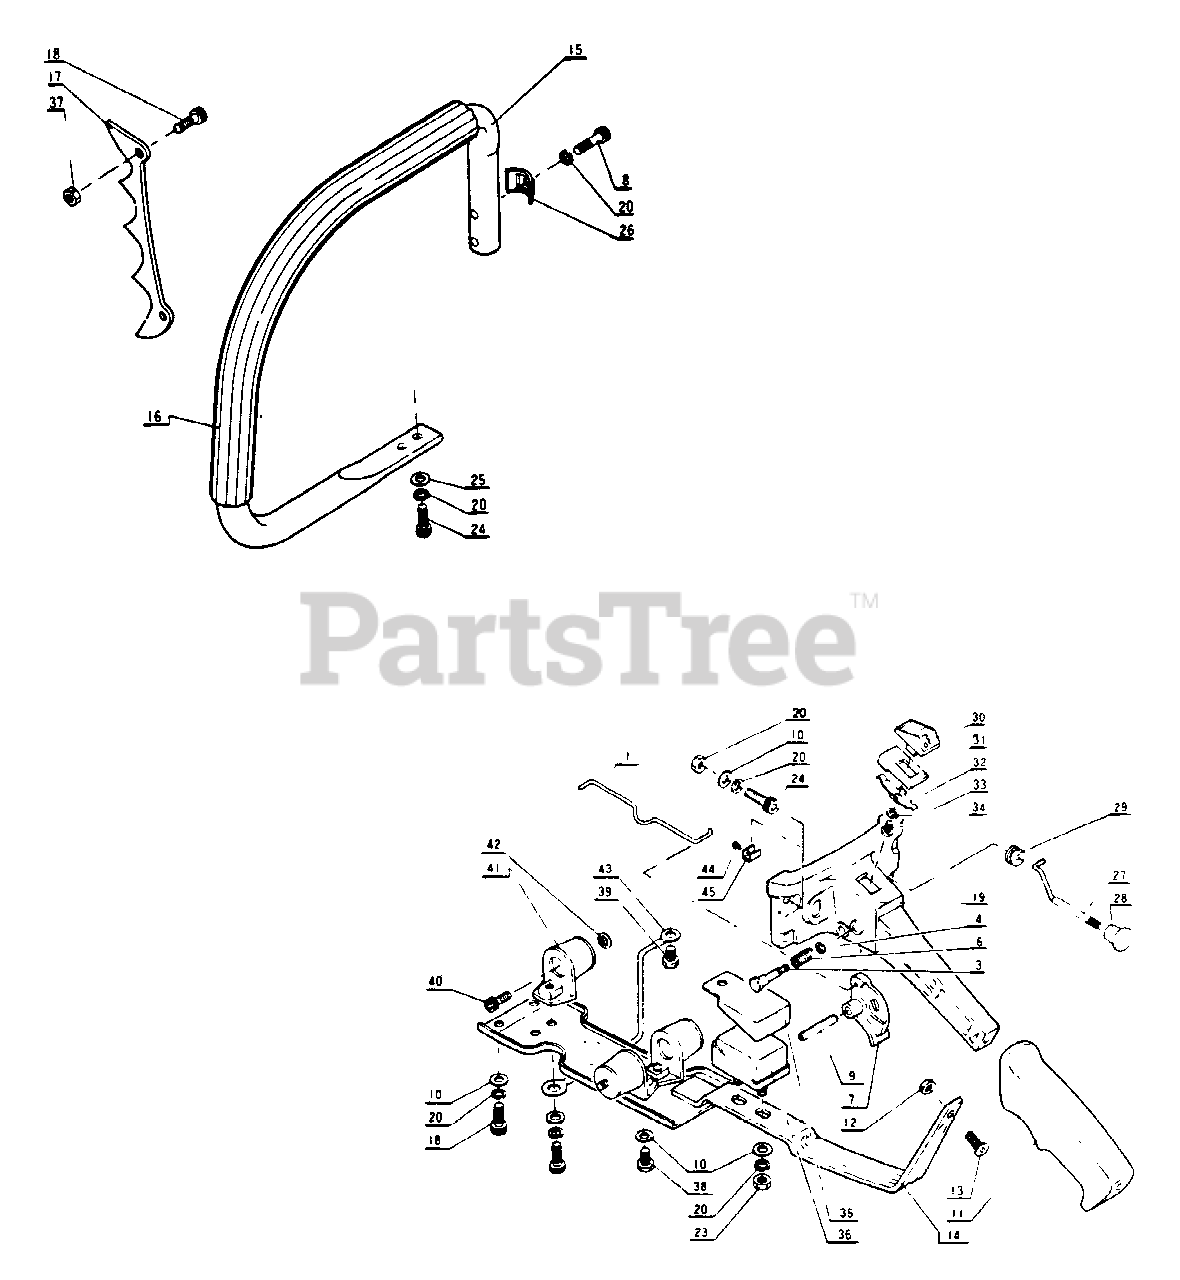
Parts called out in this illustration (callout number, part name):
1	ROD, CHOKE
3	LOCKOUT, THROTTLE
4	RING, RETAINING - 3
6	SPRING, TRIGGER
7	TRIGGER, THROTTLE
8	BOLT - 5X25
9	PIN
10	WASHER - 5
11	COVER, HANDLE
12	LOCKNUT - 5
13	BOLT
14	SUPPORT, HANDLE
15	HANDLE - FRONT
16	GRIP, HANDLE
17	SPIKE
18	BOLT
19	HANDLE - RIGHT
20	BOLT - 5X16
21	BOLT - 5X16
24	BOLT
25	WASHER - 5
26	Handle set plate
27	ROD, CHOKE
28	BUTTON, OIL PUMP
30	IGNITION SWITCH ASSY
31	GUIDE, SWITCH
32	CONTACT, SWITCH
33	LOCKWASHER - 4
34	SCREW - 4X8
35	Stopper B
36	Stopper A
37	NUT
38	BOLT
39	BOLT
40	BOLT
41	CUSHION
42	Seal washer
43	LEAD - GROUND
44	TERMINAL - GROUND
45	RIVET
